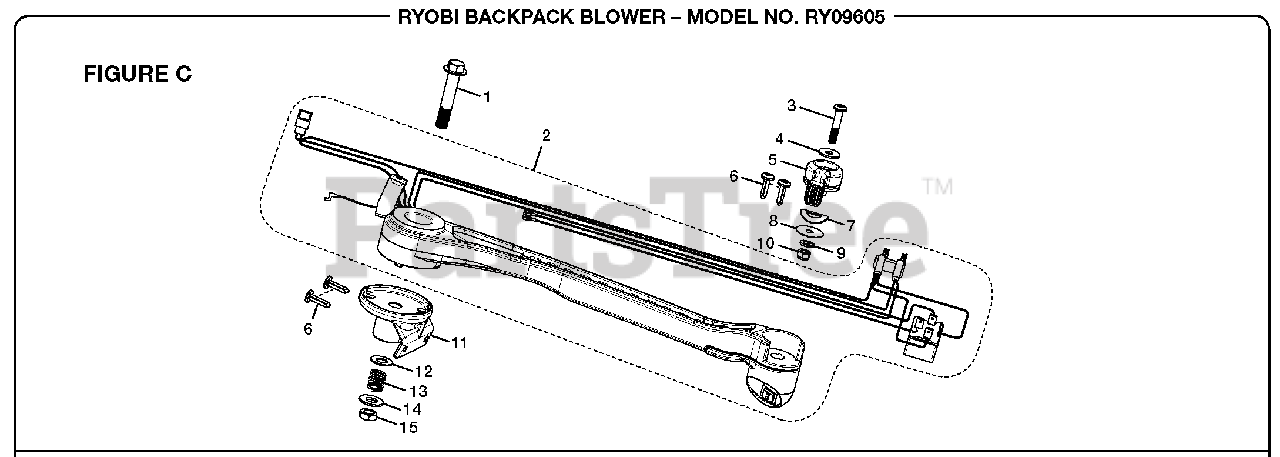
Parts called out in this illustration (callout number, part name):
1	Bolt w/washer (M10 x 53 mm, Hex Hd.)
2	Arm, Switch and Wiring Assembly
3	Screw (M6 x 32 mm)
5	Throttle Shield
6	Screw (10-14 x 3/4 in.)
7	Wavy Washer
9	Lock Washer
10	Lock Nut (M6 x 6 mm)
11	Arm Mount
13	Compression Spring
15	Hex Nut (M10 x 5 mm)
